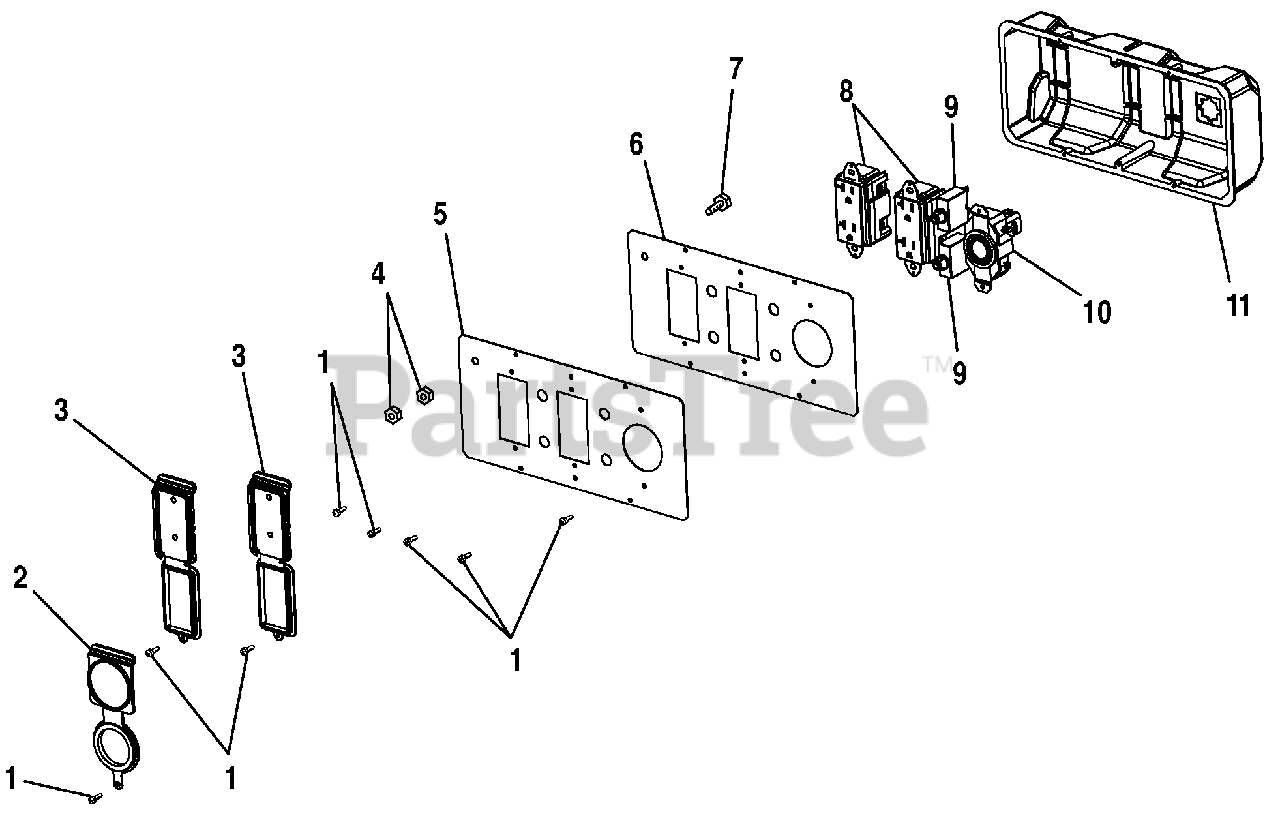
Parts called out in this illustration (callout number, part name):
1	Screw (6-20 x 3/8 in.)
2	Outlet Cover (240 Volt)
3	Outlet Cover (120 Volt)
4	Hex Nut (1/4-20)
5	Electrical Outlet Label
6	Cover Plate
7	Screw (1/4-20 x 5/8 in., Hex Hd.)
8	Duplex Receptacle (120 Volt)
9	Circuit Breaker (20 Amp, 125 Volt)
10	Twist Lock Receptacle (120/240 Volt, 20 Amp)
11	Rear Control Panel
